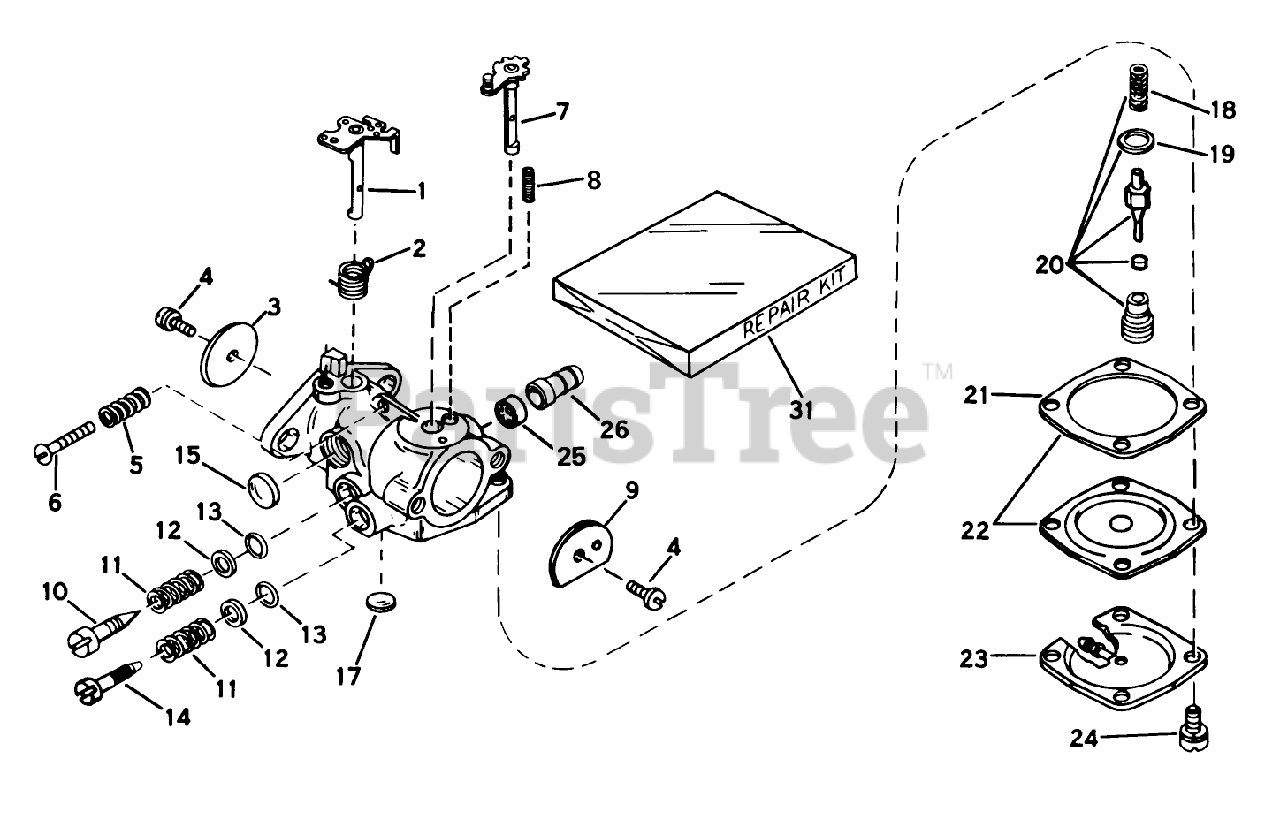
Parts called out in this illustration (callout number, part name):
1	Shaft Lever Assy., Throttle
2	Spring Return
3	Shutter, Throttle
4	Screw-Shutter
5	Spring-Tension
6	Screw-Throttle Crack Screw / Idle Speed
7	Shaft Lever Assy., Choke
8	Spring-Positioning, Choke
10	Screw-Idle Adjustment
11	Spring
12	Washer
13	ORing
14	Screw Main Adjustment
15	Plug-Welch, Idle Mixture Well
17	Plug Welch
18	Spring-Valve
19	Gasket-Valve Seat
20	Inlet Needle, Seat, Spring Gasket Assy. (lncl. #1819)
21	Gasket-Diaphragm
22	Diaphragm Ass. (Incl. No. 21)
23	Cover, Diaphragm
24	Screw, Diaphragm Cover
25	Valve Check
26	Fitting, Fuel inlet
31	Repair Kit
